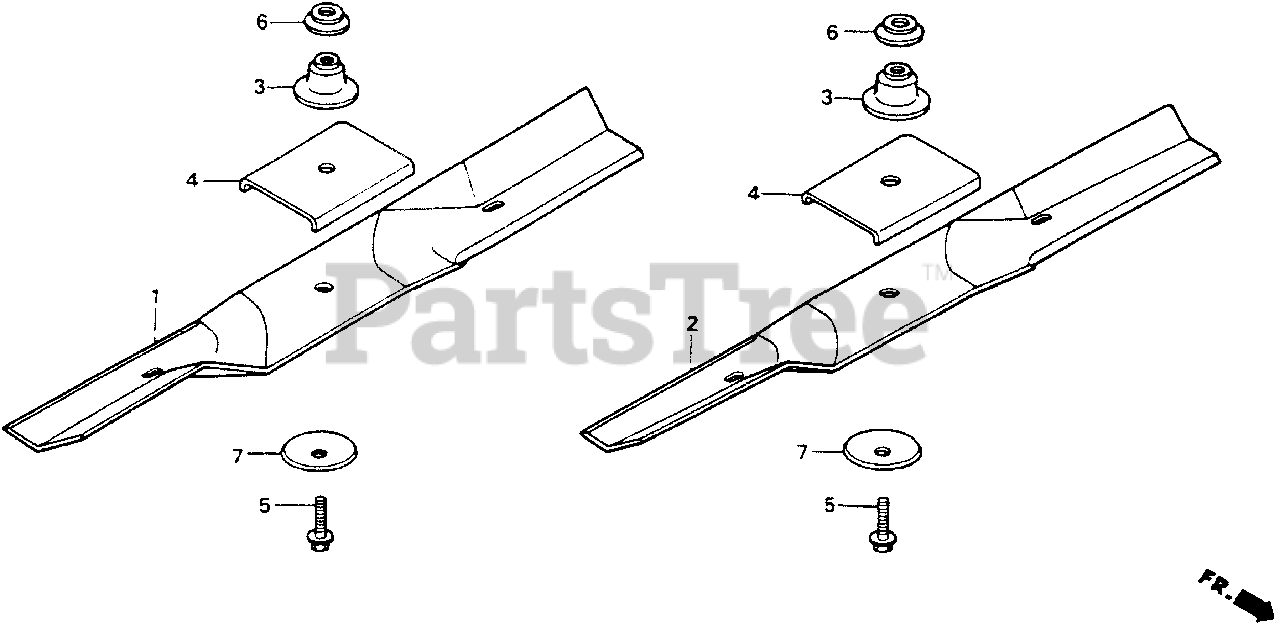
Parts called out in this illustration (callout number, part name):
1	BLADE, R. ROTARY
2	BLADE, L. ROTARY
3	HOLDER, BLADE
4	HOLDER, BLADE (B)
5	BOLT, BLADE HOLDER (10X28)
6	WASHER, BLADE HOLDER
7	WASHER, BLADE
